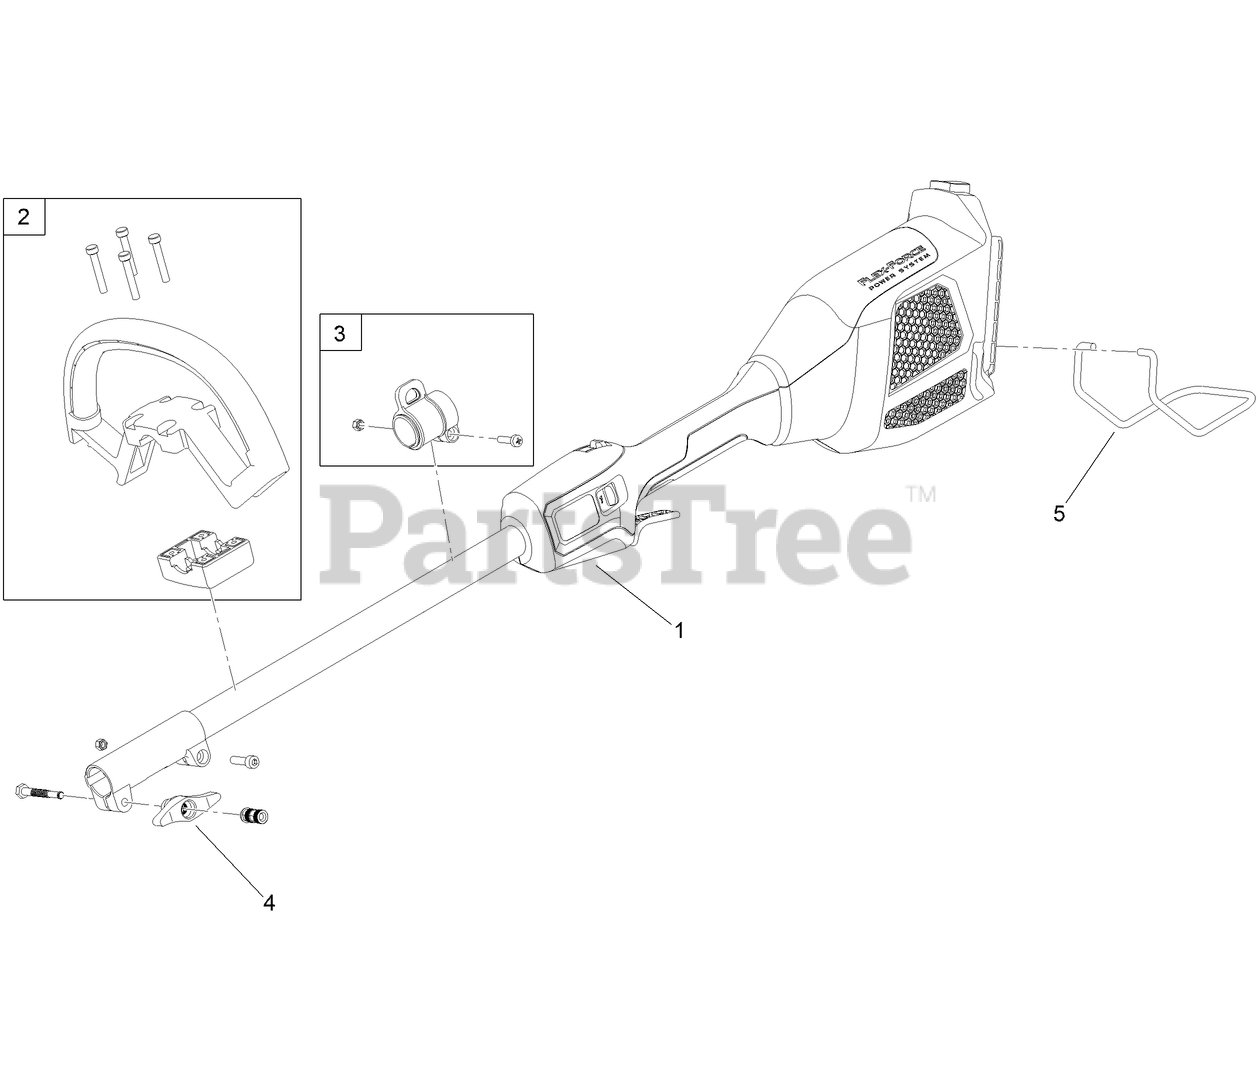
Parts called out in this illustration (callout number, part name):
1	POWER HEAD
2	HANDLE
3	COLLAR-HARNESS
4	SCREW-WING
